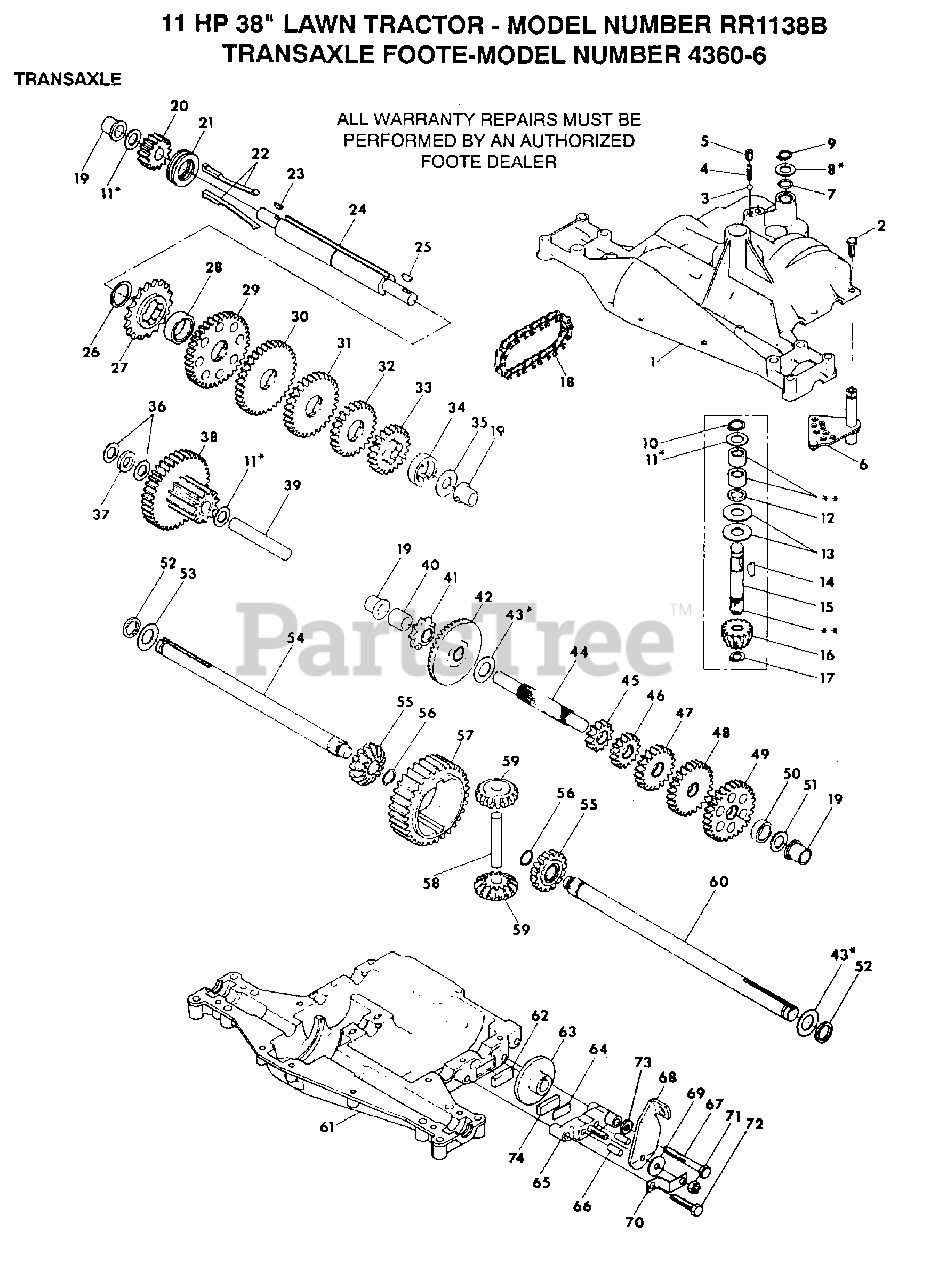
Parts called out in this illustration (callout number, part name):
1	HOUSING UPPER
3	BALL DETENT
4	SPRING, DETENT
5	SCREW, SET
6	ASSY SHIFTER
8	WASHER PLAIN
9	RING RETAINING
10	RING RETAINING
11	WASHER PLAIN
11	WASHER, PLAIN .632 X 1.00 X .026
11	WASHER, PLAIN .632 X 1.00 X .060
13	WASHER, PLAIN .632 X 1.38 X .046
14	KEY WOODRUFF #9
15	ASSY KIT INPUT SHAFT
16	PINION, BEVEL, 14 TEETH
17	RING, RETAINING
18	CHAIN, 24 PITCHES
19	BEARING, FLANGE
20	GEAR SPUR, 14 TEETH
21	COLLAR CLUTCH
22	KEY CLUTCH
23	KEY WOODRUFF #3
24	SHAFT INTERMEDIATE
25	KEY, WOODRUFF, #61
26	RING, RETAINING
27	SPROCKET, 18 TEETH
29	GEAR, SPUR, 37 TEETH
30	GEAR, SPUR, 30 TEETH
31	GEAR, SPUR, 25 TEETH
32	GEAR, SPUR, 22 TEETH
35	WASHER, PLAIN .640 X 1.37 X .061
37	SPACER .630 X 1.00 X .169
38	ASSY GEAR COMB 12&35 TEETH
39	SHAFT IDLER
40	SPACER .635 X .875 X .755
41	SPROCKET, 9 TEETH
42	GEAR, BEVEL, 42 TEETH
43	WASHER PLAIN
43	WASHER, PLAIN .758 X 1.25 X .031
44	SHAFT, DRIVE
45	GEAR, SPUR, 12 TEETH
46	GEAR, SPUR, 20 TEETH
47	GEAR, SPUR, 25 TEETH
48	GEAR, SPUR, 28 TEETH
49	GEAR, SPUR, 31 TEETH
51	WASHER, PLAIN .632 X 1.00 X .060
53	WASHER PLAIN
54	AXLE LEFT HAND
55	GEAR, MITER, 15 TEETH
56	RING, RETAINING
57	GEAR, SPUR, 32 TEETH
58	SHAFT, CROSS
59	GEAR, MITER, 15 TEETH
60	AXLE, R.H.
61	HOUSING LOWER
62	PUCK, FRICTION
63	DISC, BRAKE
65	JAW, BRAKE
66	PIN, DOWEL
67	SCREW TAPPING
68	LEVER, ACTUATING
69	WASHER, PLAIN .321 X 1.00 X .055
70	BRACKET, ANTI-ROTATION
71	LOCKNUT 5/16-24
72	SCREW TAPPING
73	WASHER PLAIN
74	PUCK, FRICTION
